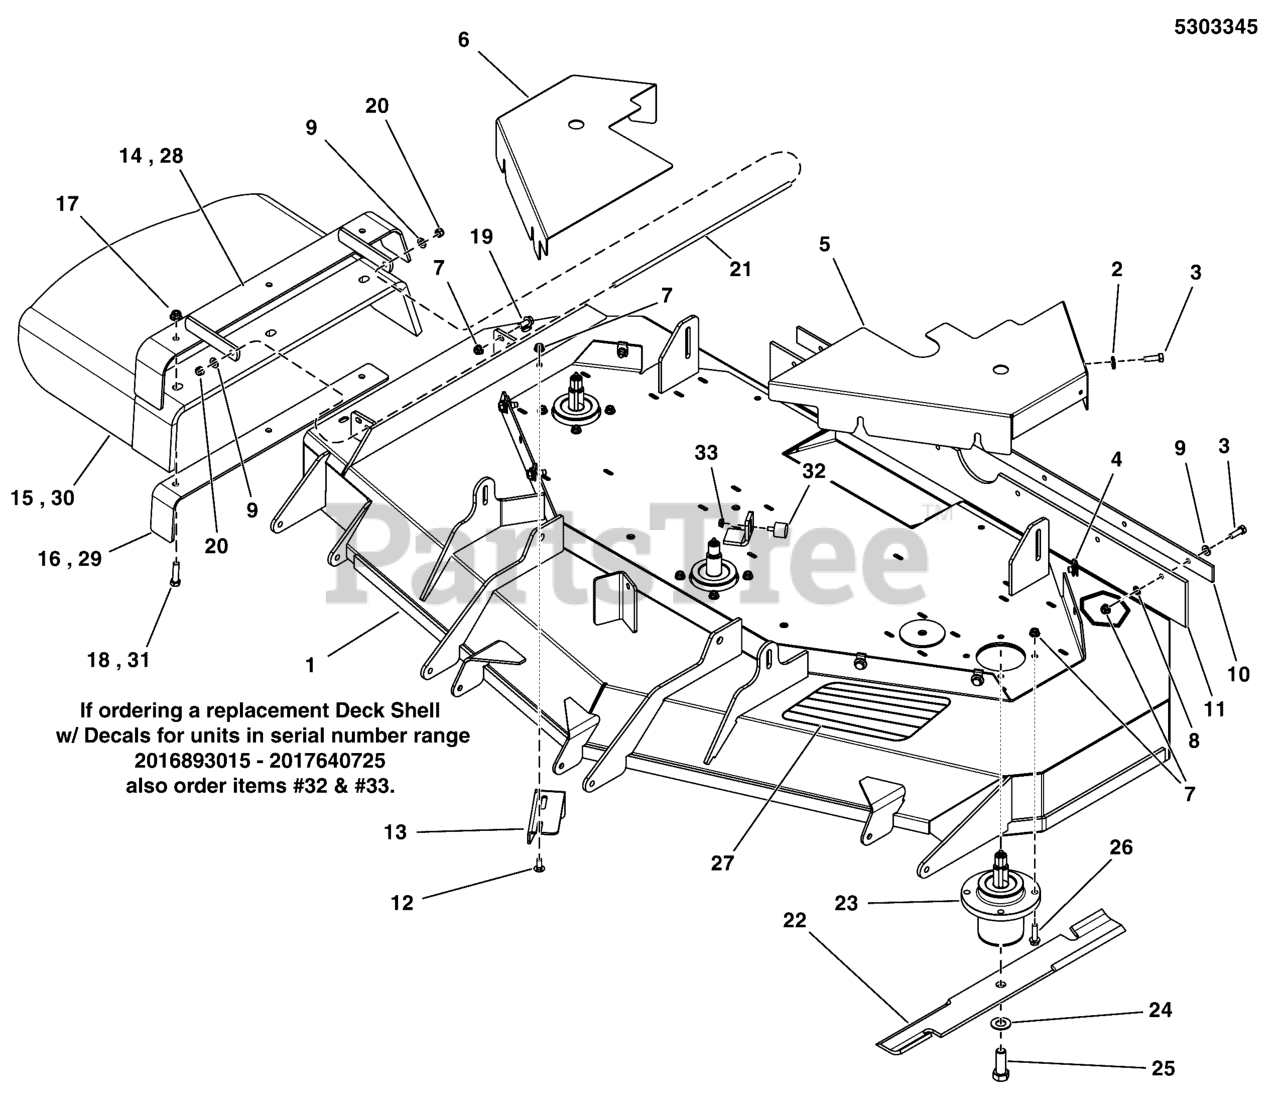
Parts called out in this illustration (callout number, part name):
1	DECK SHELL W/ DECALS, 61, S125XT
1	DECK SHELL W/ DECALS, S125XT-61, DOM
2	WASHER, 5/16" SAE
3	BOLT, 5/16-18 X 1 GD5 YZ
4	BODY CLIP, 5/16-18-7GA MATERIAL
5	PLATE, GUARD, 61, LH - RED
6	PLATE, GUARD, 61, RH - RED
7	NUT, 5/16-18 HEX NYLOCK FLANGE
8	5/16 PUSH-ON NUT RETAINER, STL, CZ
9	WASHER, 5/16" SAE
10	PLATE, SUPPORT - BLK
11	FLAP, STRIPER, 61 DECK
12	BOLT, 5/16-18 X 3/4, CARRIAGE
13	PLATE, DEFLECTOR - BLK
14	WELD, FRAME CHUTE, 61 - BLK
15	CHUTE, DISCHARGE, BEND RUBBER (SV)
16	SUPPORT, DISCHARGE CHUTE, 61/72 - BLK
17	NUT, 3/8-16 HEX NYLOCK FLANGE
18	BOLT, 3/8-16 X 1-1/2" GD5 CZ
19	BOLT, 5/16-18 X 3/4 GD5
20	NUT, 5/16-24 HEX NYLON LOCK
21	ROD, MOUNT, CHUTE 61, CZ
22	BLADE, 21 X .25 X 2.5, 1 X 3.5 (SET OF 3)
23	ASSM, SPINDLE, LOW PROFILE
24	WASHER, 5/8 GRADE 8, YZ
25	BOLT, 5/8-11 X 1-3/4 GD8
26	BOLT, 5/16-18 X 1 1/4 FLANGE
27	SAFETY WALK, 4.00 X 7.50
28	MOUNT
29	SUPPORT, DISCHARGE CHUTE - BLK
30	CHUTE, RUBBER DISCHARGE (5104442)
31	BOLT, 3/8-16 X 1-1/2, CARRIAGE, GD5, CZ
32	BUMPER, RUBBER 1/4-20
33	NUT, 1/4-20 HEX SERR. FLANGE
